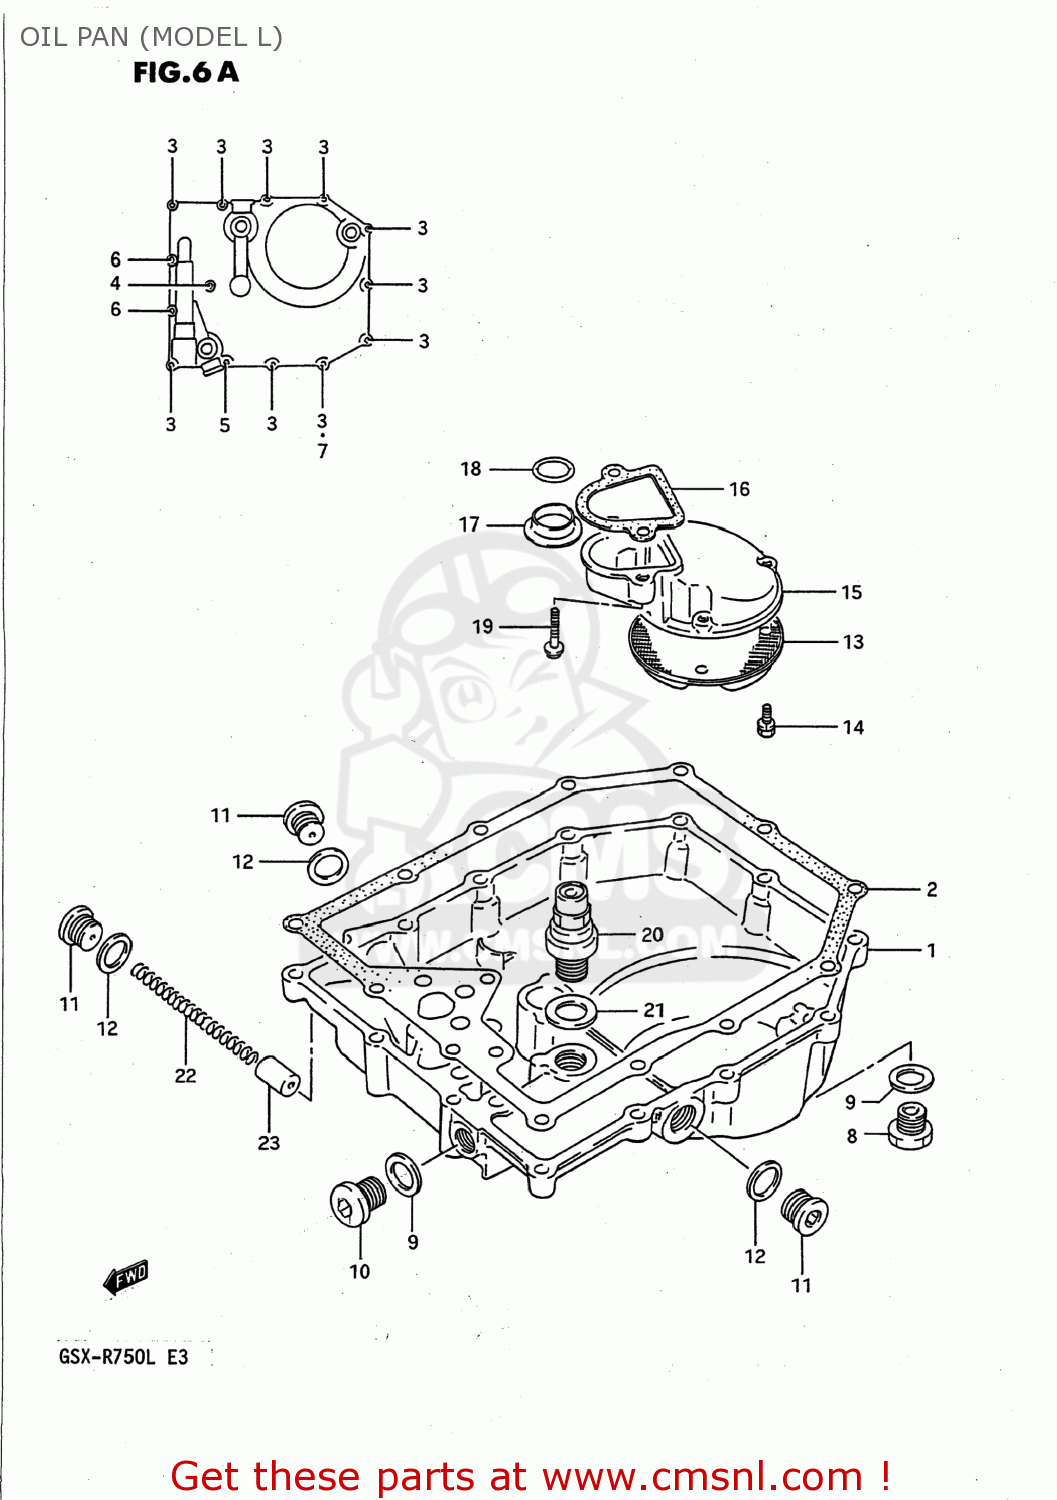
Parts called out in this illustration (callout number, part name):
1	PAN,OIL
2	GASKET,OIL PAN (NAS)
3	BOLT
4	BOLT
5	BOLT
6	BOLT
7	GASKET(5.8X11X1.2) (NAS)
8	PLUG
9	GASKET(14X19.2X2) (NAS)
10	PLUG
11	PLUG
12	GASKET(16X22X2) (NAS)
13	STRAINER,ENGINE OIL
14	BOLT
15	PROTECTOR,OIL STRAINER
16	GASKET,OIL STRAINER PROTECTOR (NAS)
17	GASKET,OIL OUTLET (NAS)
18	O RING(D:3.2,ID:17.8)
19	BOLT 6X25
20	VALVE ASSEMBLY,OIL RELIEF
21	GASKET(16X22X2) (NAS)
22	SPRING
23	PLUNGER,OIL CONTROLL
